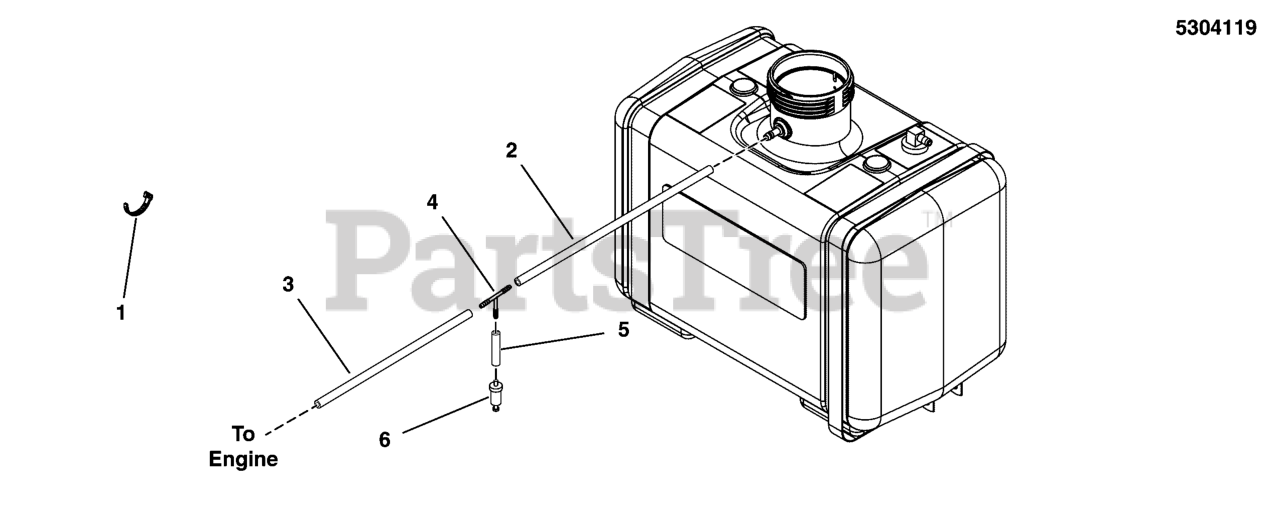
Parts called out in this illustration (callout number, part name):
1	TIE,SELF-LOCKING, 6"
2	HOSE, VAPOR, 5MM ID, 12.00 LG
3	HOSE, VAPOR, 5MM ID, 24.50 LG
4	FITTING, 3/16" TEE, BARB TYPE, HDPE
5	HOSE, VAPOR, 5MM ID, 2.00 LG
6	FILTER, FUEL
